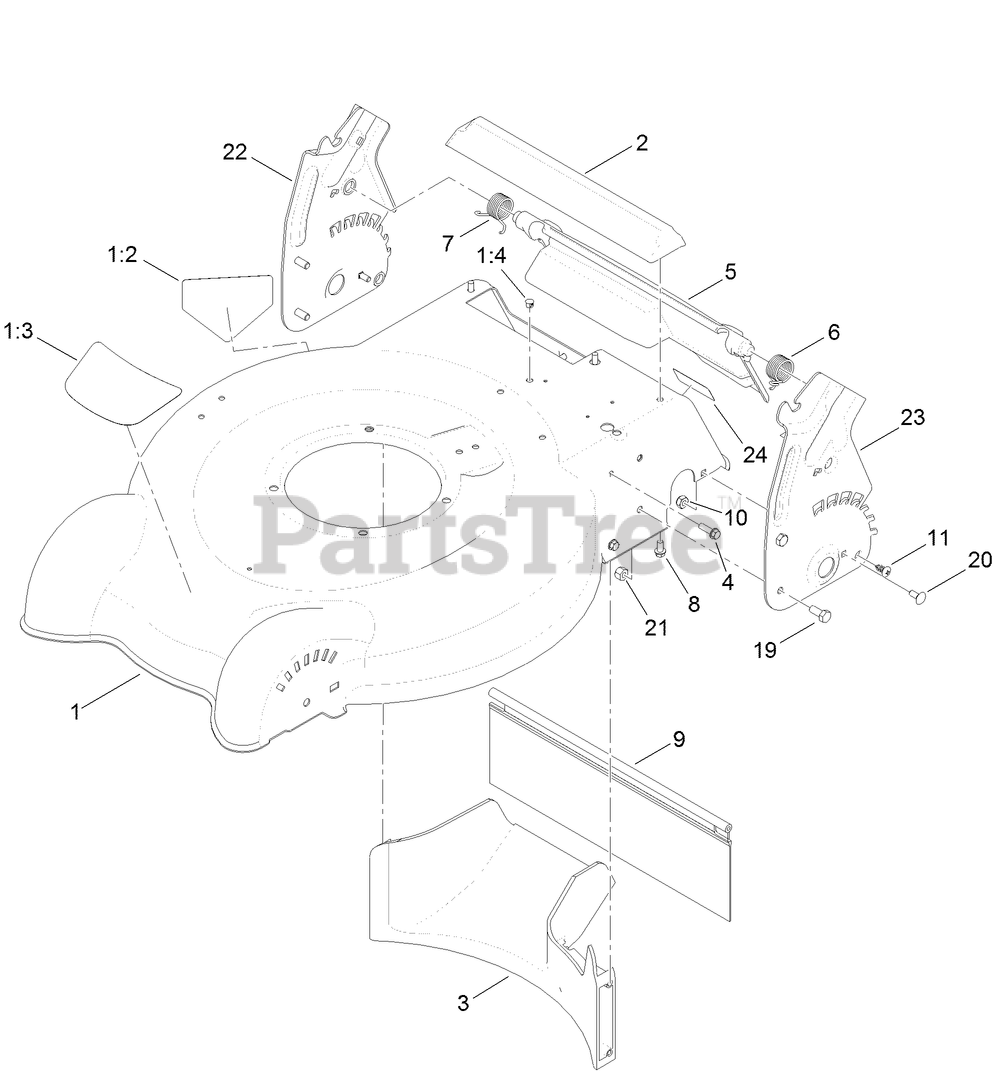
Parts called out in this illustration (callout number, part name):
1	HOUSING ASM
1:2	DECAL-DANGER
1:4	PLUG-DOME
2	CHUTE-REAR
3	BAFFLE-REAR
4	SCREW-HWH
5	REAR DEFLECTOR ASM
6	SPRING-TORSION, LH
7	SPRING-TORSION, RH
8	SCREW-PLASTITE
9	SHIELD-TRAILING
10	NUT-LOCK, NI
11	SCREW-PTH
19	SCREW-HH
20	SCREW-CARR
21	NUT-LOCK, NI
22	PLATE-HOC, LH
23	PLATE-HOC, RH
24	DECAL-LOCATION, SERVICE DEALER
